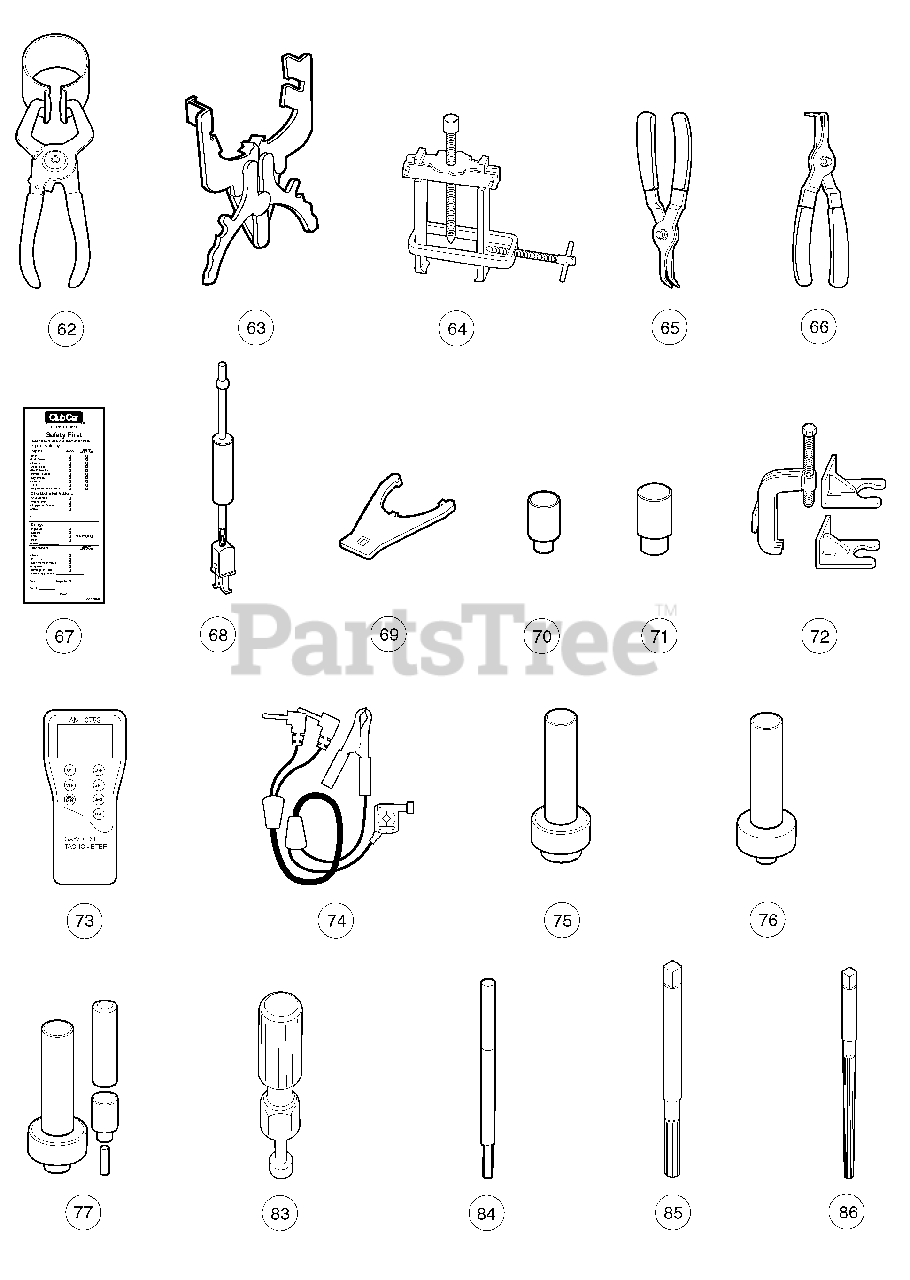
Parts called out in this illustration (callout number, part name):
62	Piston Ring Compressor Kit
63	Piston Ring Pliers
64	Puller, Special Use
65	Retaining Ring Pliers, 45 deg External
66	Retaining Ring Pliers, 90 deg Internal
67	Safety First Card (50 per pack)
68	Seal Puller
69	Spanner Wrench
70	Steering Column Bearing Press Tool
71	Steering Column Retaining Ring Tool
72	Steering Wheel Puller Tool
73	Tachometer
74	Tachometer Diesel Probe
75	Transaxle Axle Seal Tool
76	Transaxle Pinion Seal Tool
77	Transmission Tool Kit
83	Valve Clearance Adjuster Screw Holder
84	Valve Guide Driver
85	Valve Guide Reamer
86	Valve Guide Reamer, 6.6 mm
